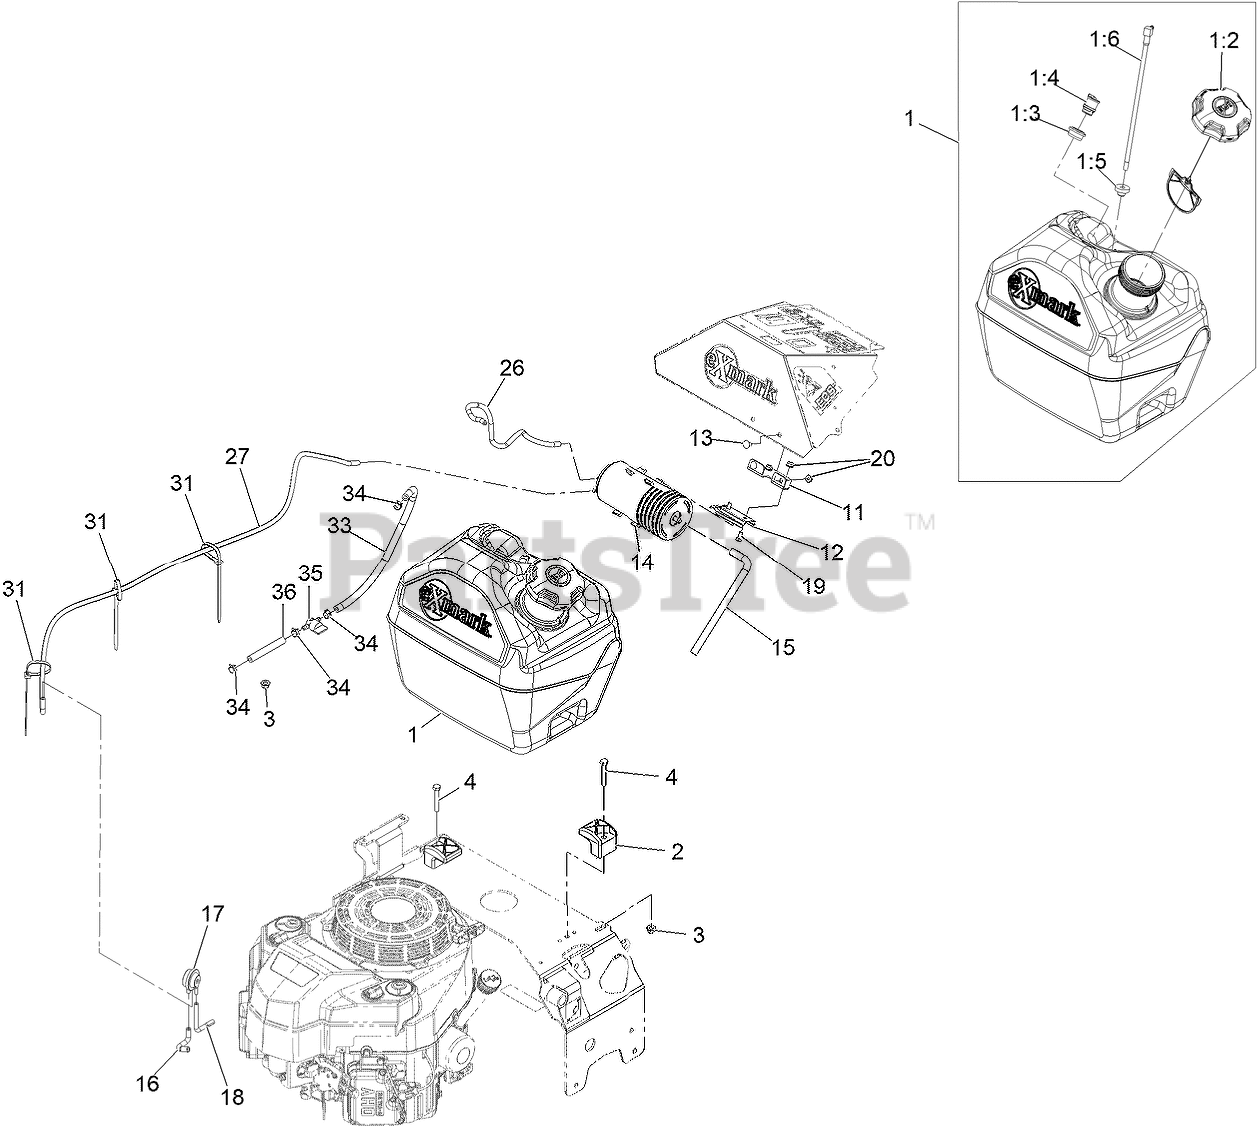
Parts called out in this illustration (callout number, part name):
1	ASM, FUEL TANK 5 GAL
1:2	CAP-FUEL, RATCHETING
1:3	GROMMET
1:4	VALVE-VENT, FUEL
1:5	BUSHING
1:6	FITTING, FUEL W/LINE AND SCREEN
3	NUT-HF, NI
4	SCREW-HH
11	BRACKET-CANISTER, CARBON
12	BRACKET-CANISTER, CARBON
13	SCREW-CARR
14	CANISTER-CARBON, 800CC
15	HOSE-VENT, CANISTER
16	HOSE-VENT, FORMED
17	VALVE-CONTROL, VACUUM
18	HOSE-VENT, FORMED
19	SCREW-HH
26	HOSE-EMISSIONS
27	HOSE-VENT, FORMED
31	TIE-CABLE
33	HOSE-FUEL
34	CLAMP-HOSE
35	VALVE-FUEL
36	HOSE-FUEL
